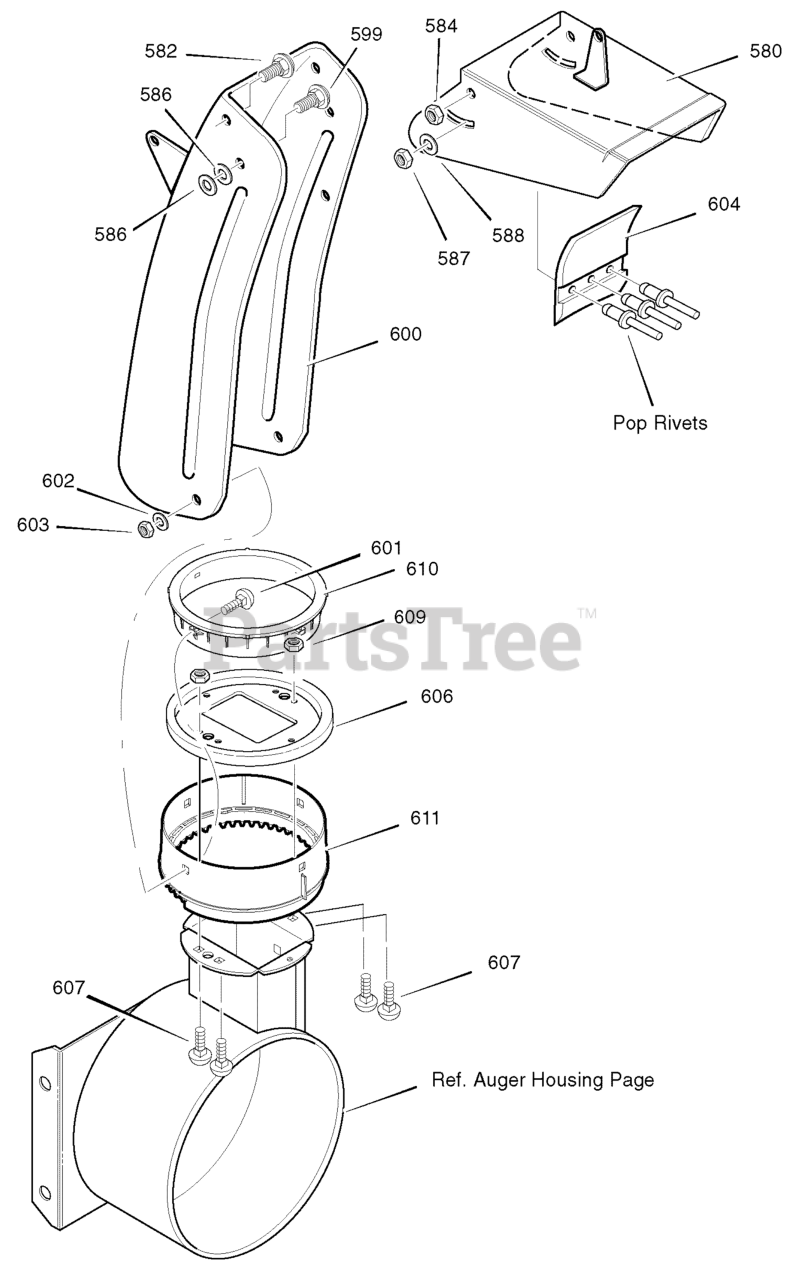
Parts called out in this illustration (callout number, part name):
580	CHUTE, UPPER W/REMOTE
582	SCREW, 5/16-18 x 0.75
584	NUT
586	WASHER, PLASTIC
587	NUT
588	WASHER, PLASTIC
599	SCREW, 5/16-18 x 0.75
600	CHUTE, LOWER W/REMOTE
601	BOLT
602	WASHER, FLAT
603	NUT
606	CHUTE COLLAR
610	RETAINER, RING INNER
611	RETAINER, RING OUTER
